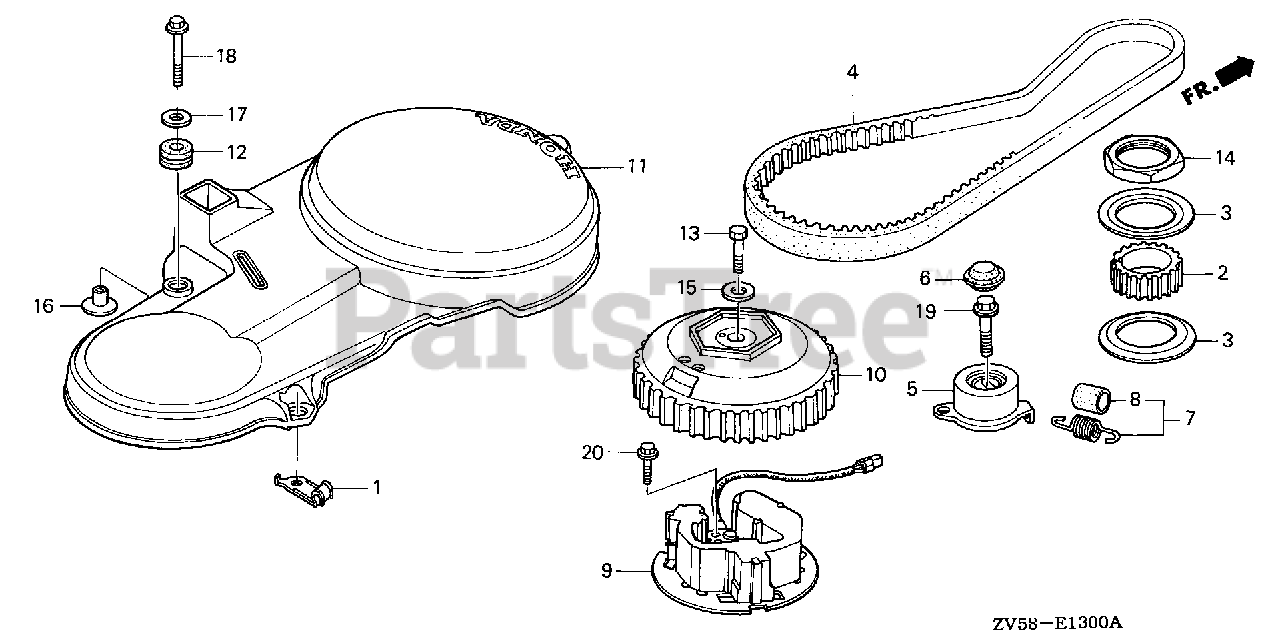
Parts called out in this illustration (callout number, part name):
1	CLAMP, TUBE
2	PULLEY, TIMING
3	PLATE, TIMING BELT GUIDE
4	BELT, TIMING
5	TENSIONER, TIMING BELT
6	CAP, TIMING BELT TENSIONER
7	SPRING, TIMING BELT ADJUSTING
8	BOOT, SPRING
9	COIL ASSY., PULSER
10	ROTOR, PULSER (44T)
11	COVER, FLYWHEEL
12	GROMMET, CASE (LOWER)
13	BOLT, FLANGE (10X32)
14	NUT, LOCK (48MM)
15	WASHER (10X28X5)
16	COLLAR, MODULE IGNITION CONTROL CASE (CDI)
17	WASHER, PLAIN (6MM)
18	BOLT, FLANGE (6X25)
19	BOLT, FLANGE (10X38)
20	BOLT, FLANGE (6X12)
